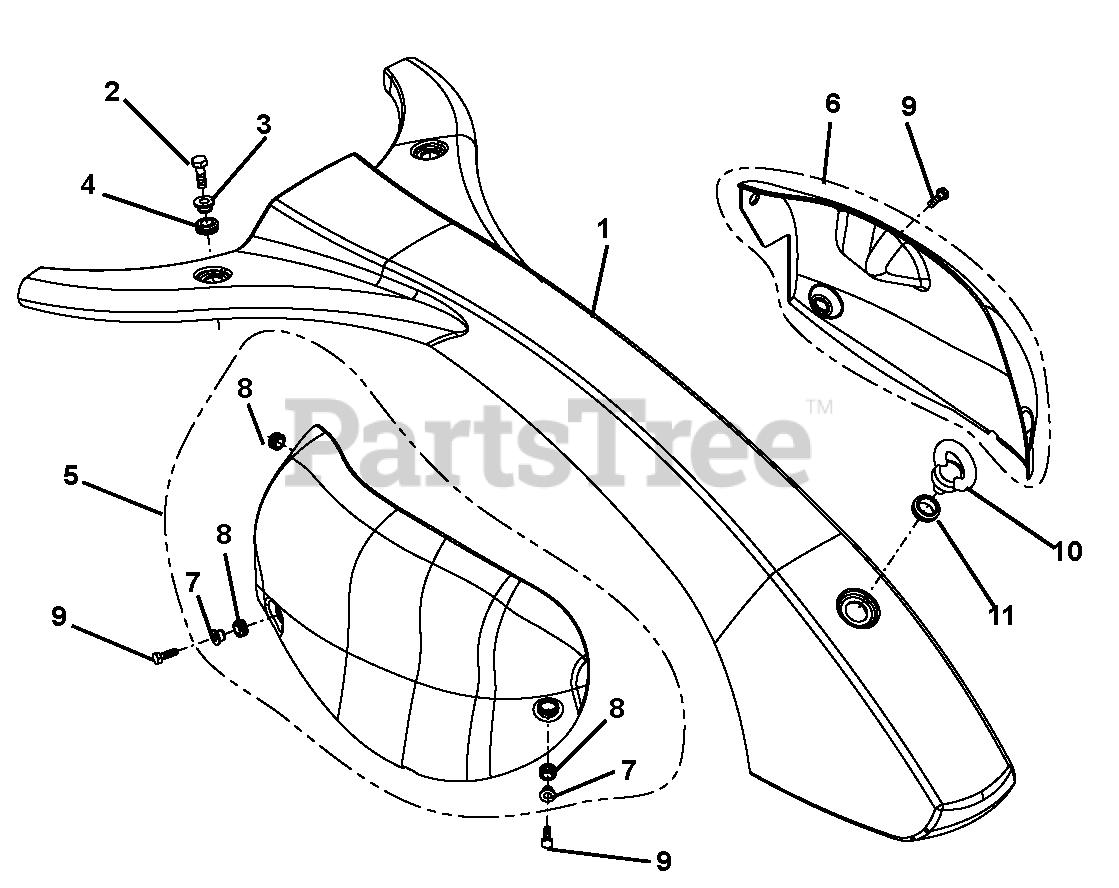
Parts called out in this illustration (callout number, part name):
1	Bonnet Handlebar
2	Bolt, Hex D933 M8 x 25
5	Bonnet Assembly (Includes 7 - 8)
6	Bonnet Assembly (Includes 7 - 8)
9	Bolt, Hex D933 M6 x 20
10	Screw, Ring D580 M12 x 20
11	Grommet, N553 18 x 27 x 22
